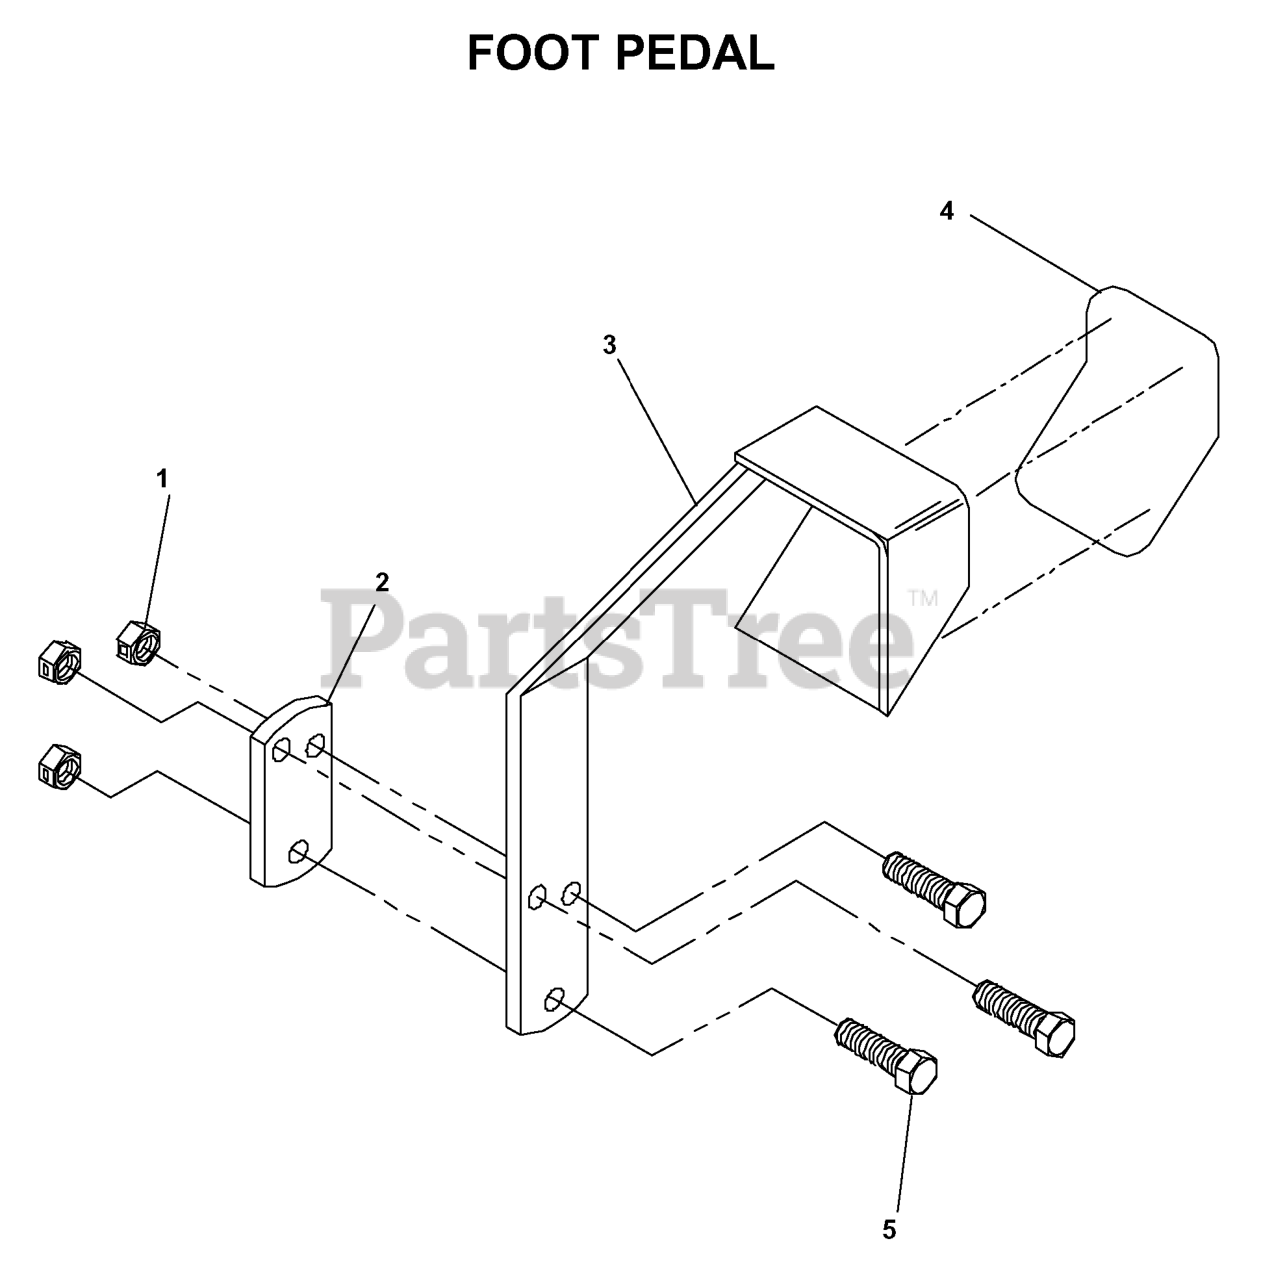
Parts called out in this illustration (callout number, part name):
1	NUT 3/8-16 NYLOC
2	TIGHTENING PLATE BLK
3	LIFT PEDAL BLK
4	ANTI-SKID PAD
5	HCS 3/8C X 1 1/2
